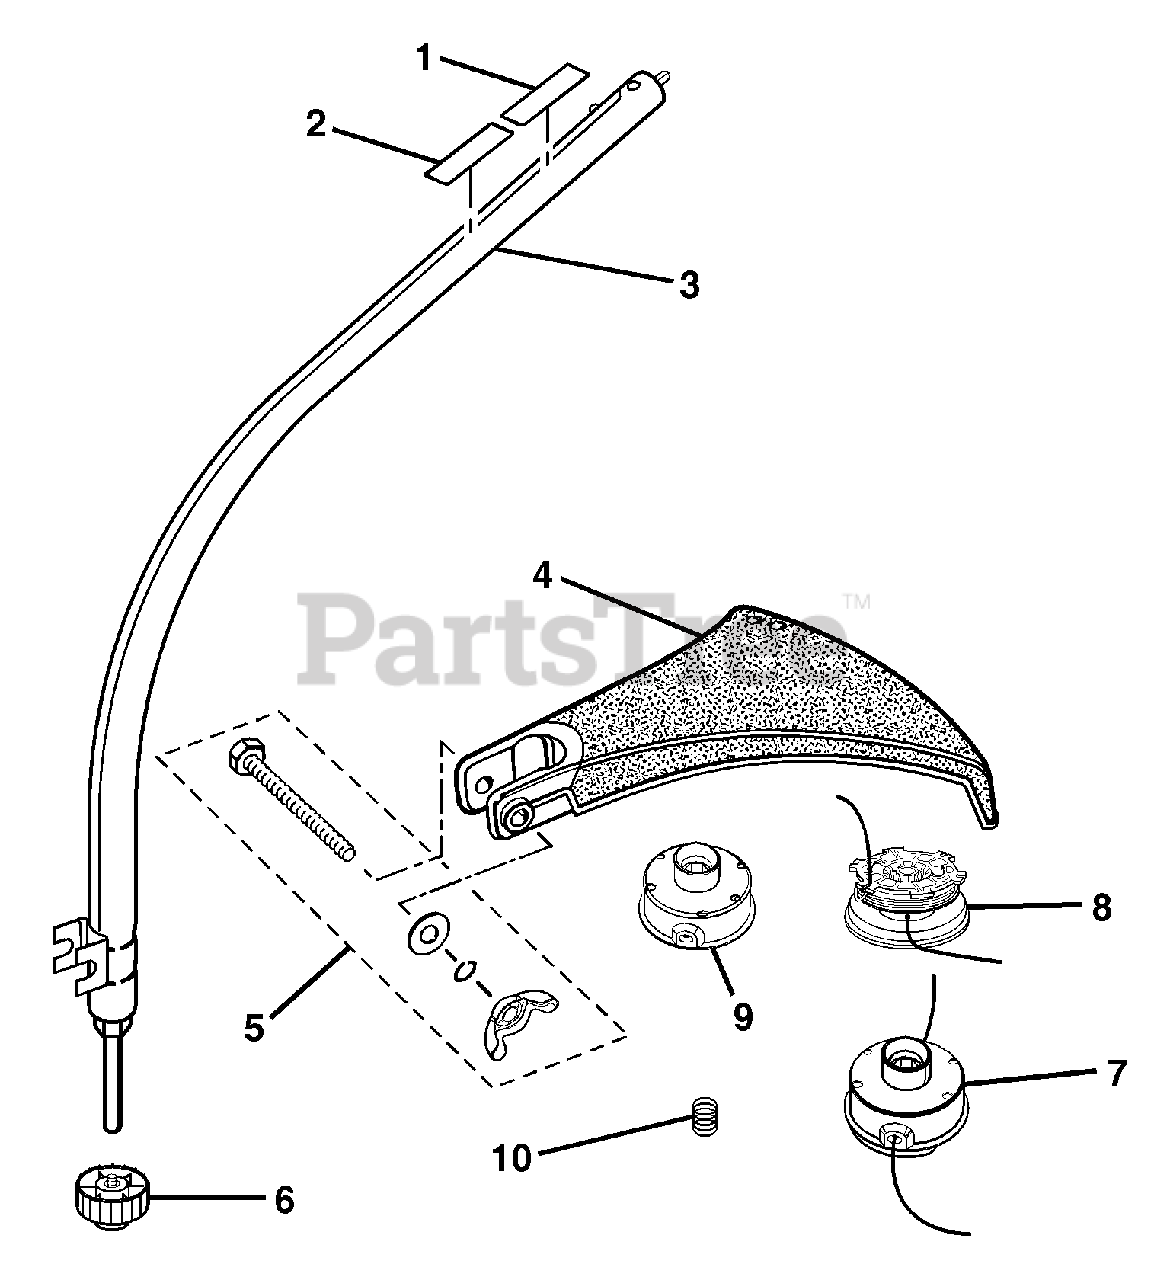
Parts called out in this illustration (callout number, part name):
1	EXPAND-IT LABEL
2	WARNING LABEL
3	CURVED SHAFT ASSEMBLY
4	GRASS DEFLECTOR
5	FASTENER PARTS KIT
6	SPOOL RETAINER (RHT) (ITEM NO AP04106)
7	COMPLETE STRING HEAD (.080 in.) (ITEM NO AP04114)
8	SPOOL AND STRING (.080 in.) (ITEM NO AH04112)
9	HOUSING AND EYELET
